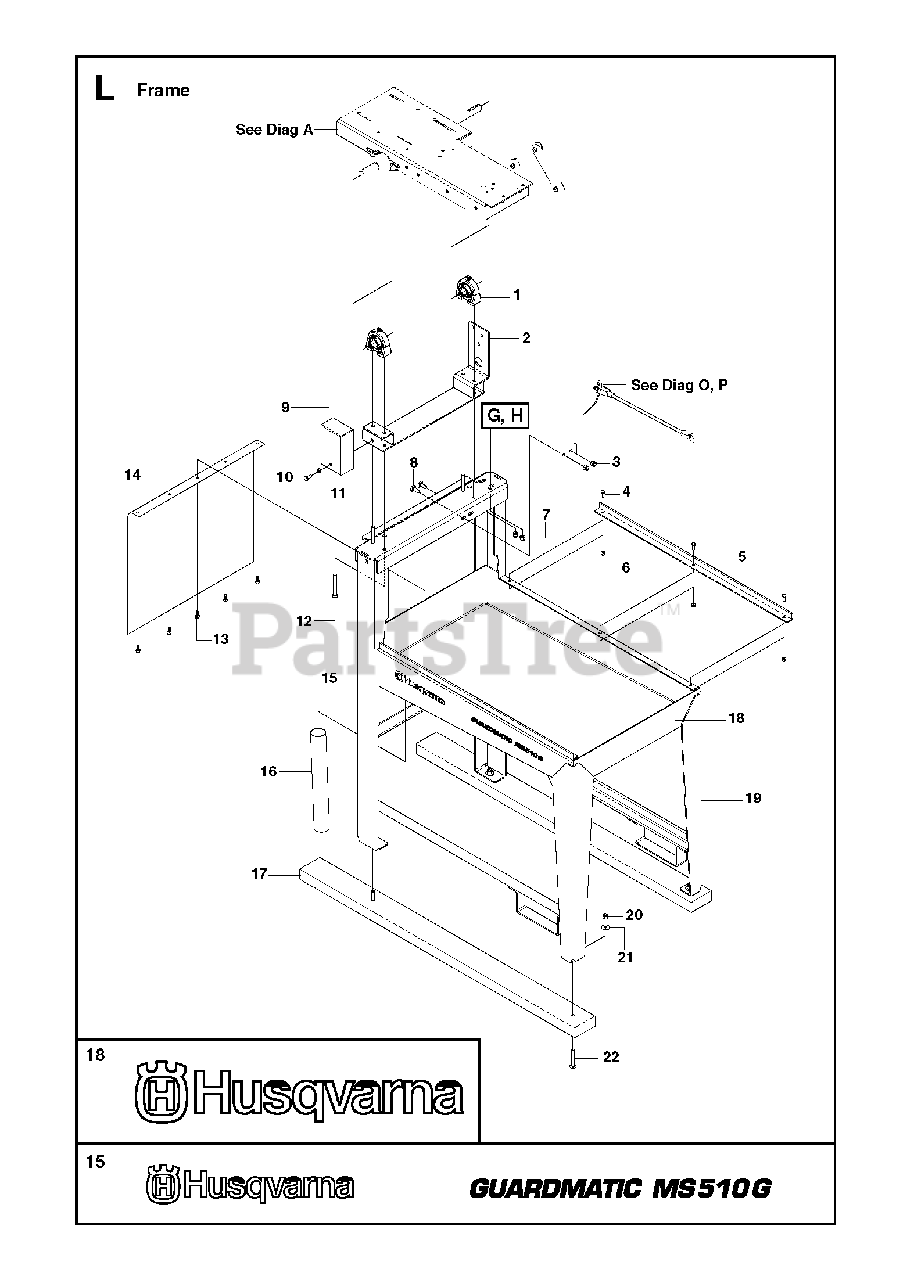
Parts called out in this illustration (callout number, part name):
3	NUT
6	NUT
7	NUTHonda GX390 11HP Only
10	SCREW
11	WASHER
